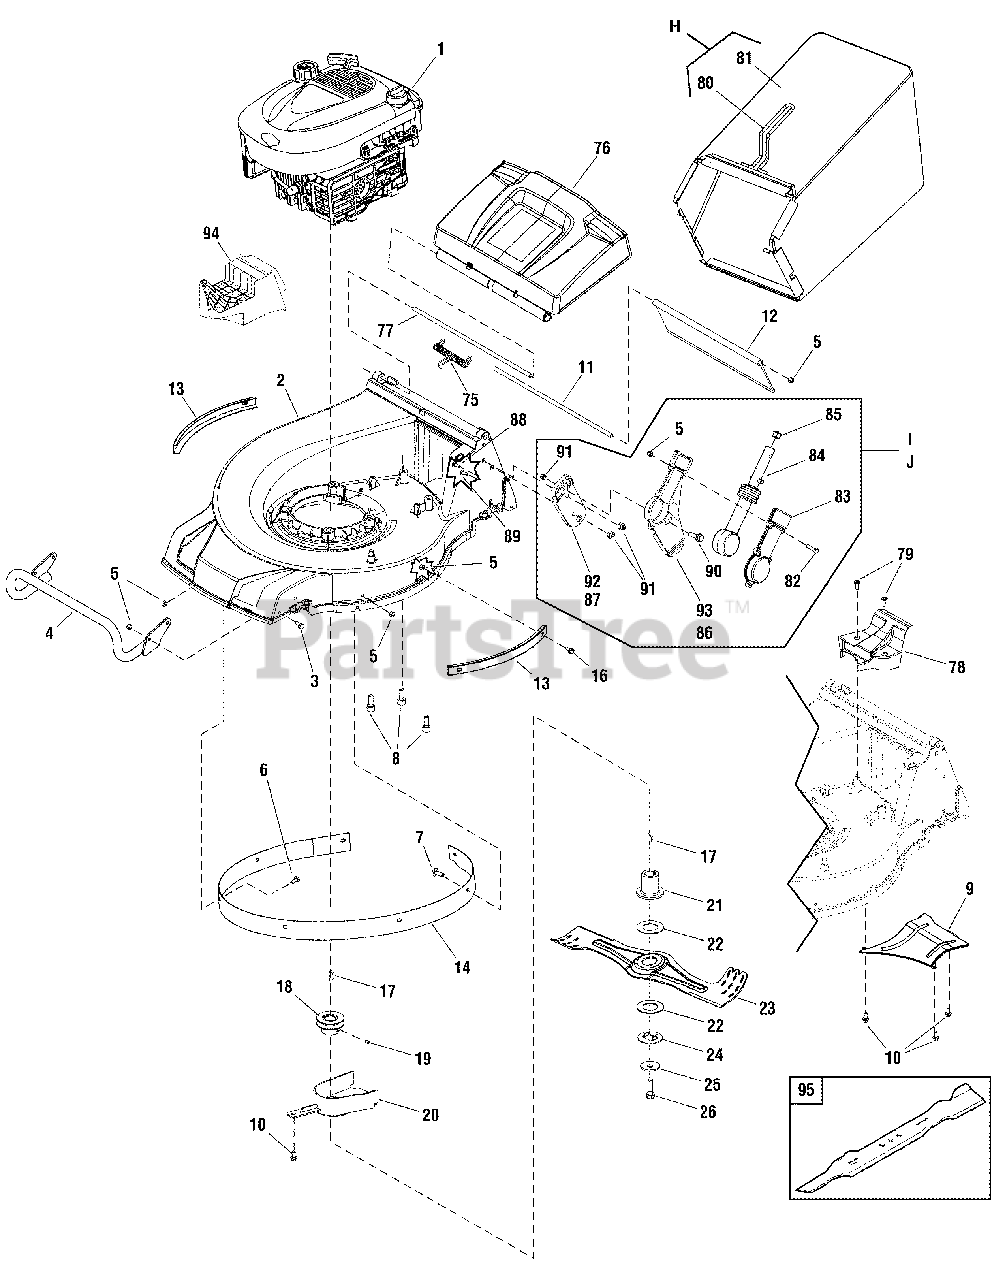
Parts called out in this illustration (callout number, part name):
1	* ENGINE, 750 Series, Briggs & Stratton
2	DECK, 21"
3	BOLT, Hex Flange
4	BUMPER, 21"
5	NUT, Hex, Nylon Insert, Torque Type
6	SCREW, Truss Head, Cross Recessed
7	SCREW, Truss Head, Cross Recessed
8	SCREW, Inner Hexagon, Round Head, Tapping
9	DEFLECTOR, Lower
10	SCREW, Hex Flange, Tapping
11	SHAFT, Rear Deflector
12	DEFLECTOR, Rear
13	SHIELD, Outer
14	SHIELD, Inner Ring
16	BOLT, Hex Flange
17	KEY, Woodruff
18	PULLEY, Engine
19	SCREW, Inner Hexagon Recessed
20	SHIELD, Lower Belt
21	ADAPTOR, Blade
22	DISC, Friction
23	BLADE, 21"
24	CLIP
25	SPRING, Dishing
26	BOLT, Blade
75	SPRING, Torsion
76	COVER, Rear
77	SHAFT, Rear Cover
78	SHIELD, Upper Pulley
79	SCREW, Inner Hexagon Tapping
80	FRAME, Grass Catcher
81	BAG, Grass Catcher
82	BOLT, Hexangular, Full Thread
83	COVER, Bracket
84	AVS ASSEMBLY
85	PLUG, AVS
86	BRACKET, Right
87	BASE, Right Bracket
88	BOLT, Carriage
89	BOLT, Carriage
90	BOLT, Hex Flange
91	NUT, Hex, Nylon Insert, Torque Type
92	BASE, Left Bracket
93	BRACKET, Left
94	PLUG, Mulch, 21"
95	BLADE, Mulch, 21"
H	GRASS CATCHER ASSEMBLY
I	BRACKET ASSEMBLY, Right
J	BRACKET ASSEMBLY, Left
